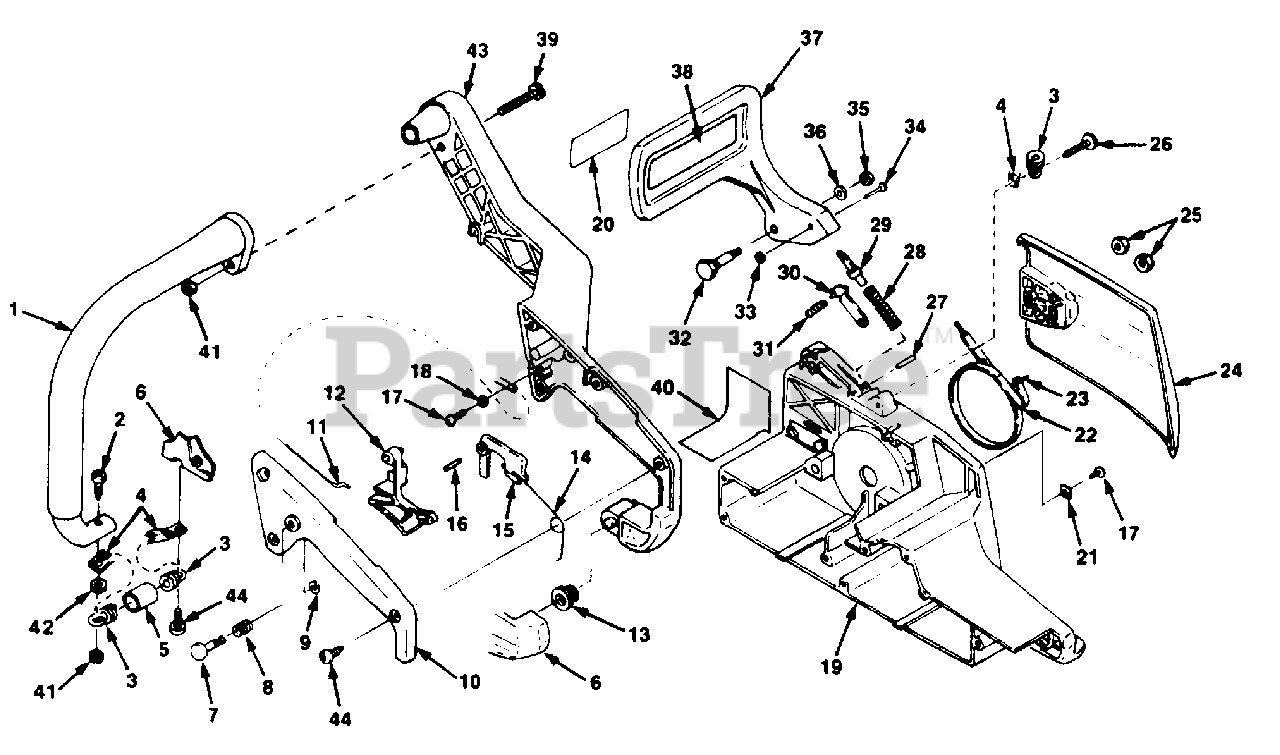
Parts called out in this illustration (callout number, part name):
1	HANDLE BAR
4	RETAINER- Spring
6	HOUSING- Starter side
7	PIN-Throttle lock
8	SPRING- Compression
9	RING- Retaining
10	COVER- Rear handle
11	CABLE- Throttle
12	TRIGGER-Throttle
13	ISOLATOR
14	SPRING- Throttle
15	LOCK- Throttle
16	PIN- Dowel
19	HOUSING- Drive side
20	LABLE- Kick back
21	RETAINER
22	BRAKE BAND ASSEMBLY
24	COVER- Drive case
25	NUT- Hex
26	SCREW- (8-16 x 5/8")
28	SPRING- Compression
29	ADJUSTER- Brake
30	BRAKE LATCH ASSEMBLY
31	SPRING- Coil
32	SCREW- Shoulder
33	RING- Retainer
35	NUT- (M5)
37	GUARD- Hand
38	DECAL- Safety
40	DEFLECTOR- Heat
41	NUT- Hex
42	WASHER
44	SCREW- (8-16 x 5/8")
